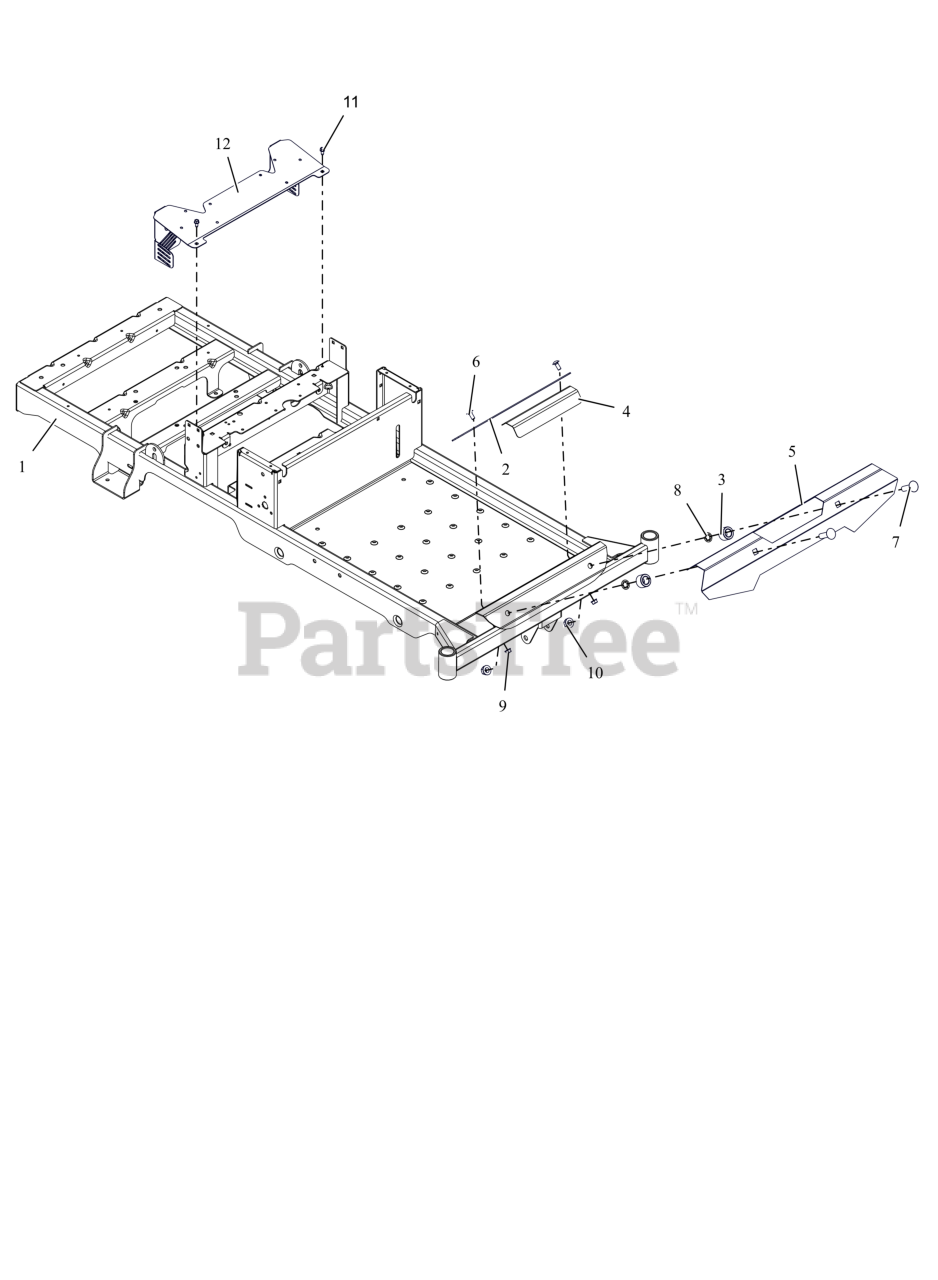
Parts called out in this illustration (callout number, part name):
1	WLDMT- FRAME
2	GRIP, ADHESIVE (1" X 16" BLK)
3	TUBE, UPPER CONTROL PIVOT
4	GRIP, STEP
5	FOOTREST, RED
6	BLT, RHSSN.31-18X.750 G5 ZCC
7	BLT,RHSN .50-13X1.75 G5 ZCC
8	NUT-PUSH, .50
9	NUT,LK-CTR-FLG .31-18 GF ZCC
10	NUT-LK-CTR-FLG .500-13 GG ZCC
11	SCR-TAP .25-20X.50 HWH ZCC
12	PLATE, FAN GUARD CE (BLACK)
